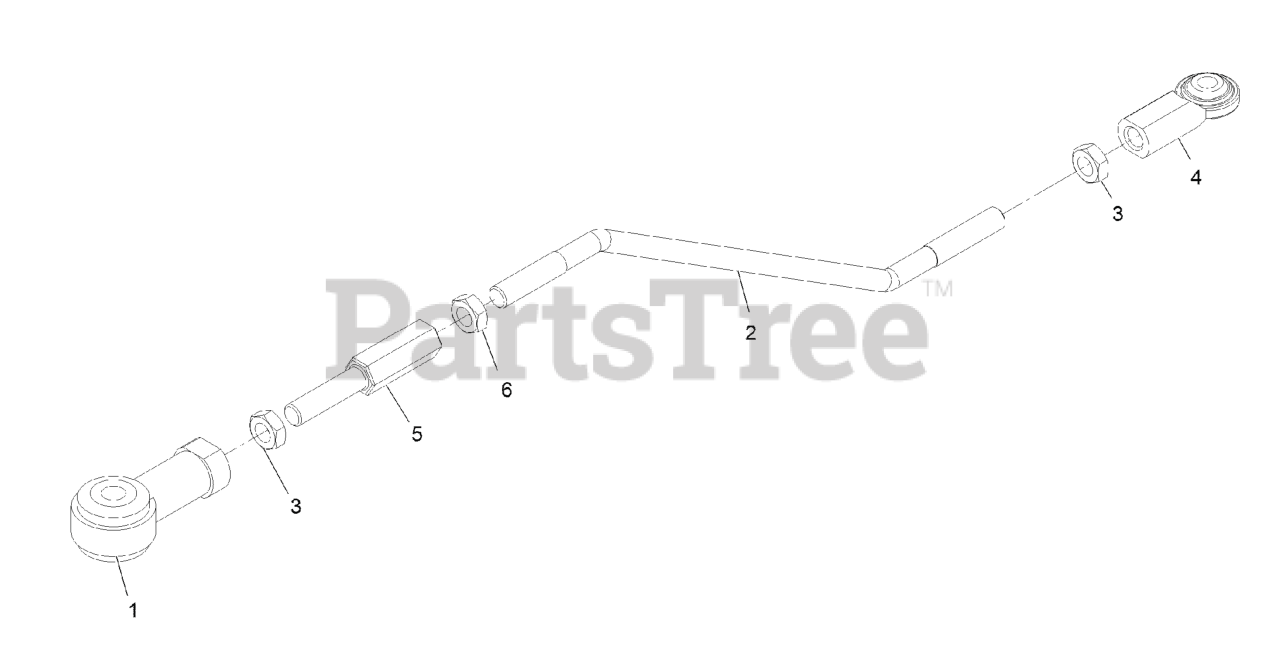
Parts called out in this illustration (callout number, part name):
1	END-ROD, ISOLATED
2	ROD-LINKAGE, REAR
3	NUT-HJ
4	JOINT-BALL, END
5	ROD-ADJUSTMENT
6	NUT-HEX JAM, LH
